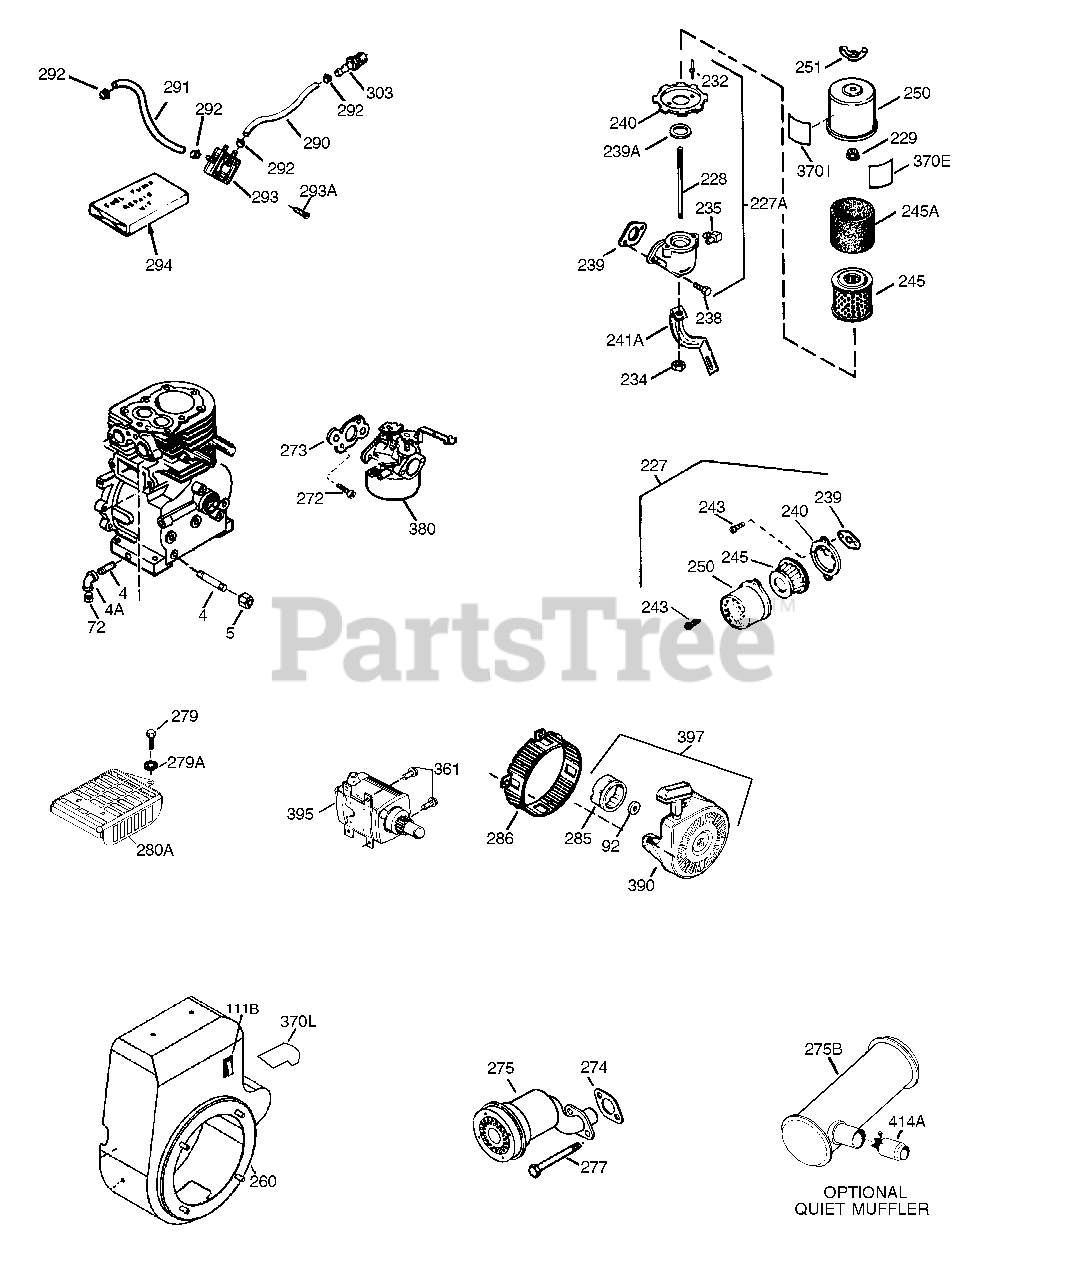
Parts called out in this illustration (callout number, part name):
72	Oil Drain Plug (Sq. hd., 1/4-18)
92	Lock Washer
151A	Valve Spring Cap
227A	Air Filter Elbow Ass'y. (Inc. 228, 23 2, 239A & 240)239&242)
228	Stud, 1/4-20 x 8.1
229	Nut, 1/4-20
232	Pop Rivet (1/8" Dia.) Purchase Locall y
235	Air Cleaner Elbow Fitting
238	Screw, 10-32 x 7/8"
239	* Air Cleaner Gasket
239A	* Air Cleaner Gasket
241A	Air Filter Bracket
245	Air Filter
245A	Air Filter (Poly)
250	Air Cleaner Cover
251	Wing Nut, 1/4-20
260	Blower Housing
285	Starter Cup
290	Fuel Line (8.62")
291	Fuel Line
292	Fuel Line Clamp
293	Pulse Pump
294	Pulse Pump Repair Kit (Walbro pumps o nly)
303	Fuel Fitting
380	Carburetor (Incl. 184)
390	Rewind Starter NOTE: This engine cou ld have been built with 590704 starte r.
702	Screw, 5/16-18 x 1-25/32"
900	Replacement Engine, 756335A Order Fro m 71-999
900	Replacement Short Block, 756316B Orde r From 71-999
